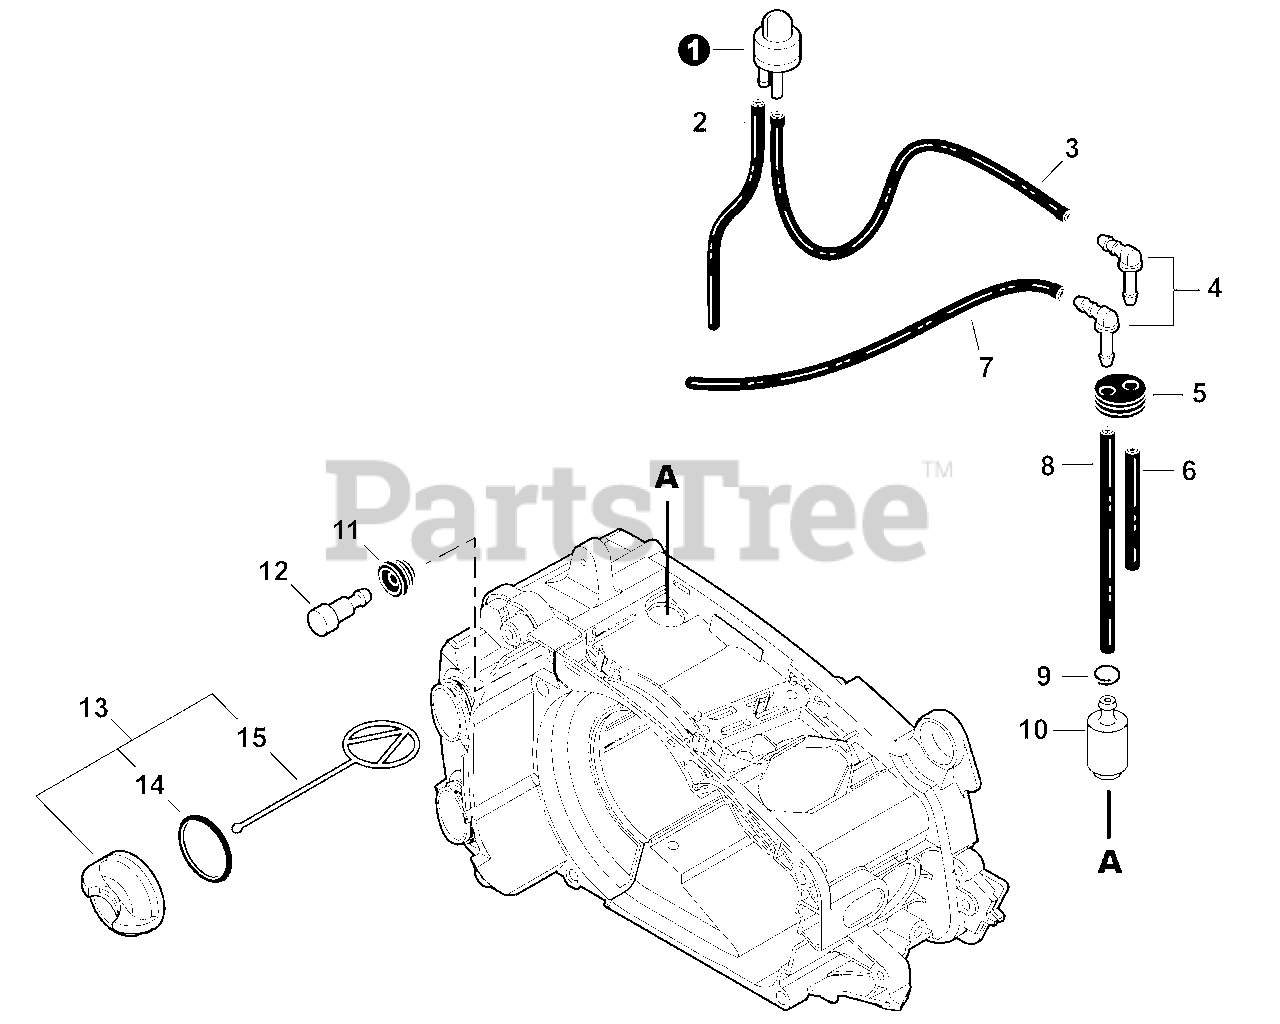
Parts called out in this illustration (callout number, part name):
1	BULB, PURGE
2	PIPE 2.4×5×180 - BLACK
3	PIPE 2.4×5×400 - BLACK
4	CONNECTOR, PIPE
5	GROMMET, FUEL
6	PIPE 2.4×5×15 - BLACK
7	PIPE 3×5×265 - BLACK
8	PIPE 3×5×140 - BLACK
9	CLIP Ø6
10	FILTER, FUEL
11	GROMMET, FUEL
12	VENT ASSY
13	CAP ASSY, FUEL - ORANGE
15	CONNECTOR, CAP L= 60 MM
